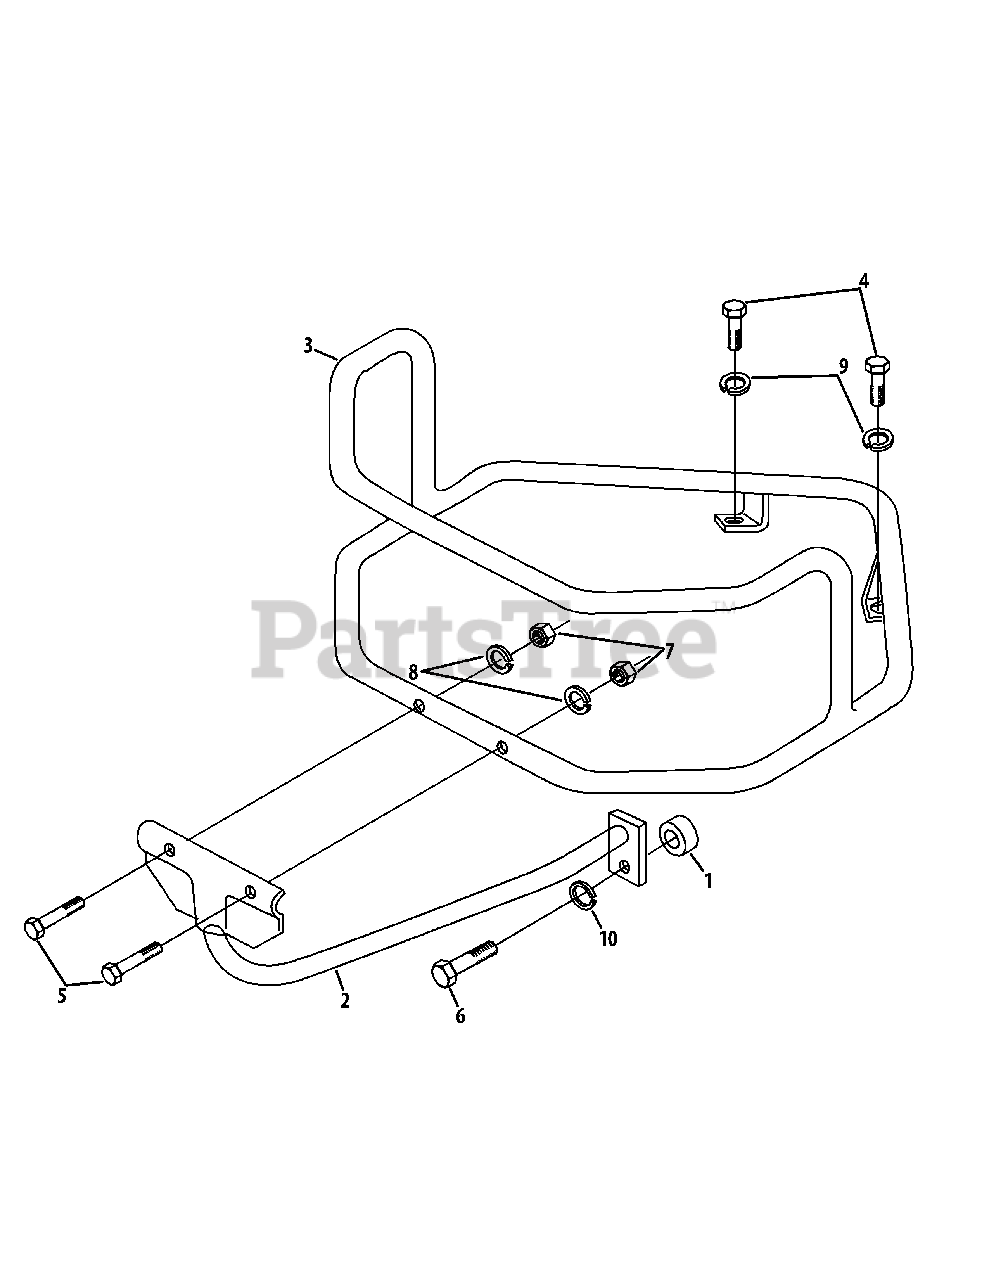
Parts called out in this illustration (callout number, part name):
1	Spacer, 1.0 x .546 x .5
2	Bottom Bumper Brace
3	Bumper Guard
4	Hex Screw, 3/8-16 x 1.00
5	Hex Screw, 5/16-18 x 1.50
6	Hex Screw, 1/2-13 x 1.50
7	Hex Nut, 5/16-18
8	Lock Washer, 5/16"
9	Lock Washer, 3/8"
10	Lock Washer, 1/2"
